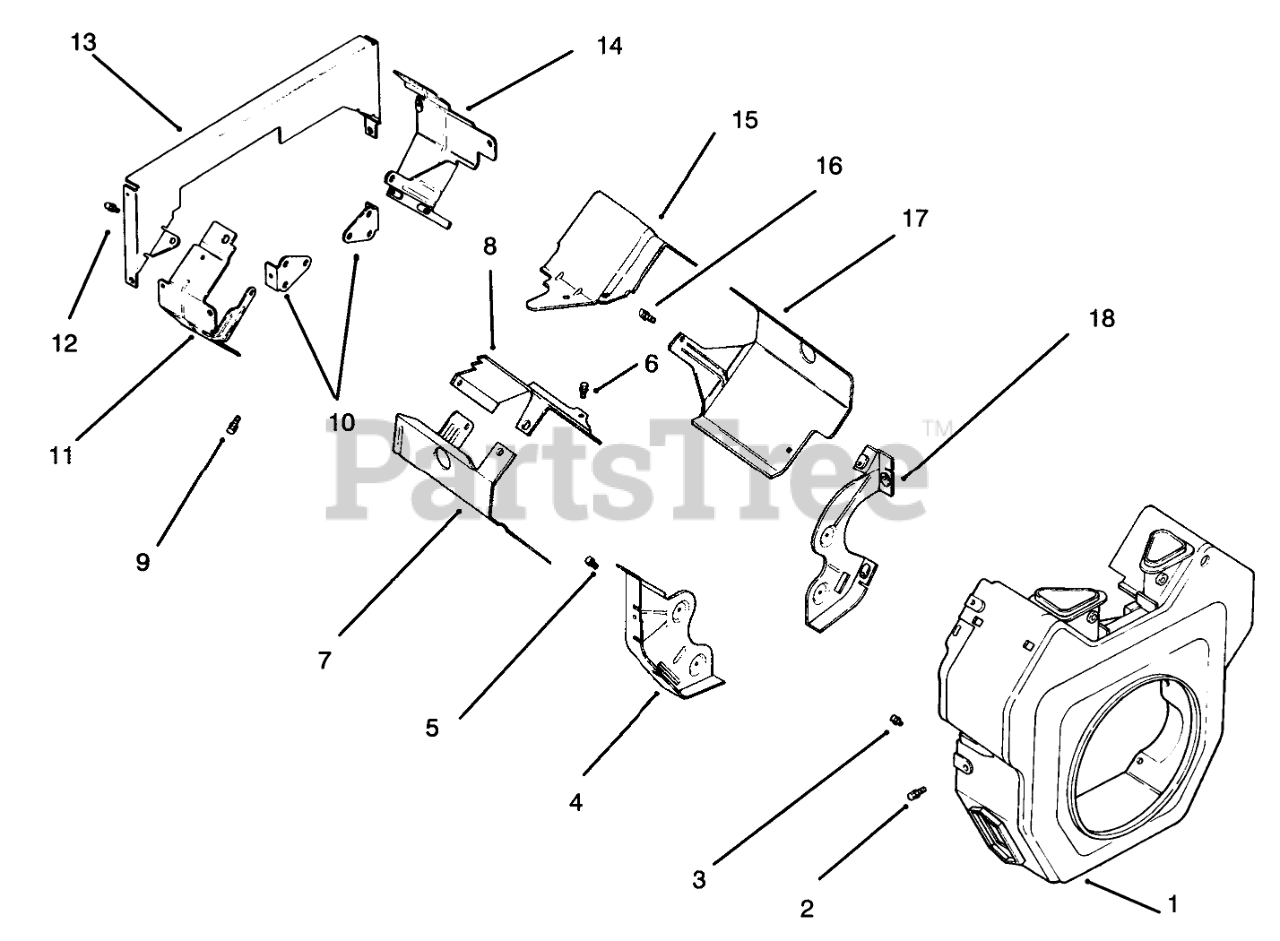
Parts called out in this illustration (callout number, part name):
1	Housing-Blower
3	Screw
4	Plate-Backing #2 side
5	Screw
6	Screw
7	Baffle-Cylinder Barrel #1 side
8	Baffle-Valley #1 side
9	Screw
10	Bracket-Support
11	Baffle-Ducted Air #1 side
13	Plat-Ducted Air Backing
14	Baffle-Ducted Air #1 side
15	Baffle, Valley #2 side
17	Baffle-Cylinder Barrel #2 side
18	Plate-Backing #1 side
